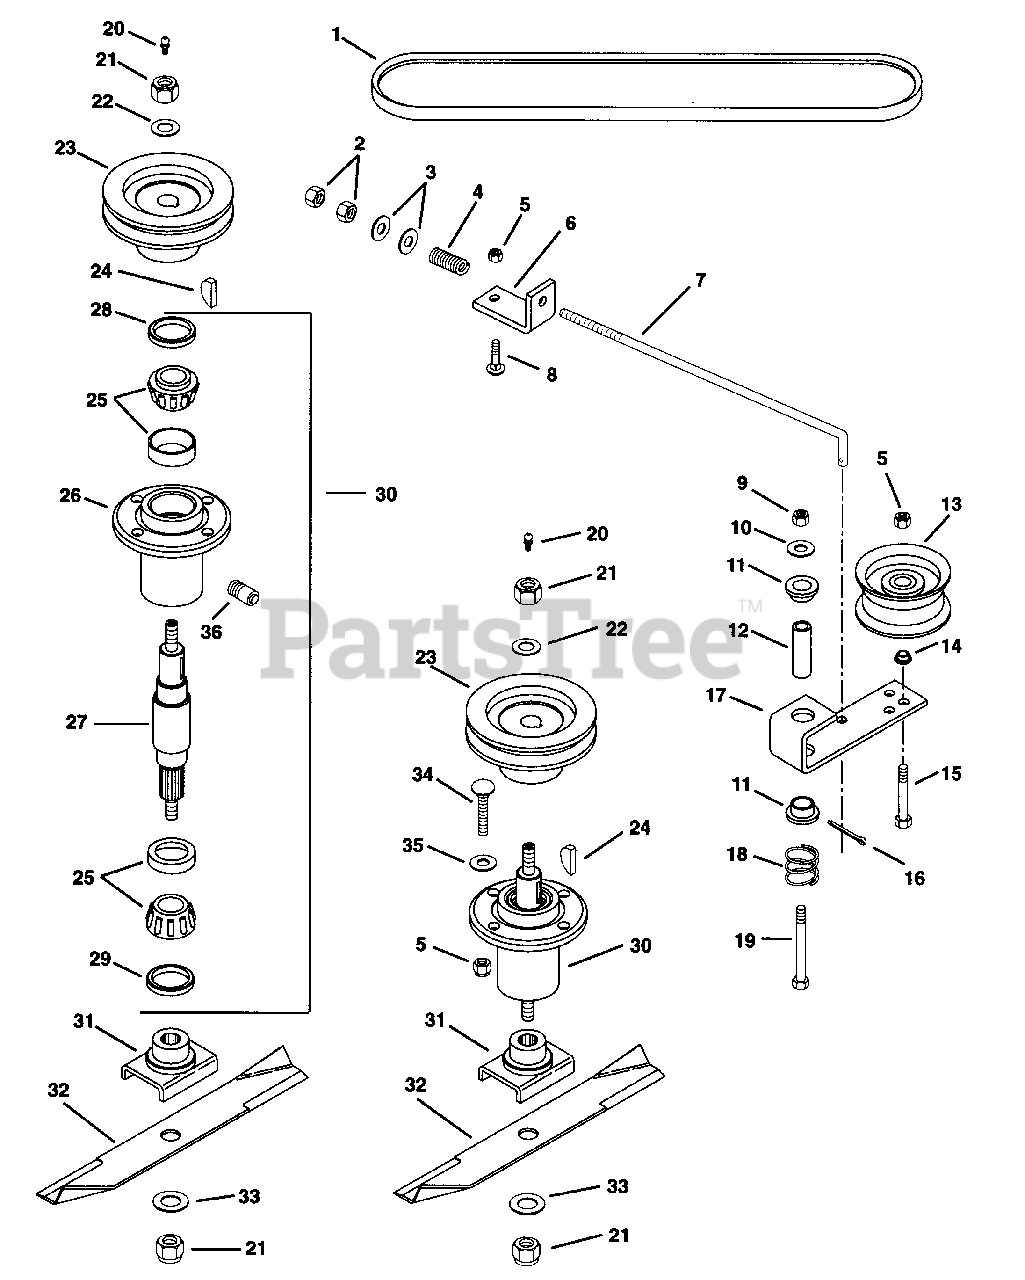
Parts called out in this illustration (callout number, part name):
1	V-Belt 4L-Section
2	Nut-Hex .375-24 Grade 2
3	Washer-Flat-Steel .406 x .812 x .065
4	Spring-Compression .125 x .78 x 1.00
5	Nut-Locking-Nylon .375-16 Grade 2
6	Bracket, Belt Tensioner
7	Rod, Idler 72" Mower
8	Bolt-Round Head Square Neck .38-16 x 1.0
9	Nut-Locking .50-13
10	Washer-Flat-Steel .531 x 1.250 x .100
11	Bushing-Flange .762 x 1.0 x .580 x 1.48
12	Bushing, Steel .560 x .750 x 2.44
13	Idler-Flat 4-6.87 x .38
14	Bushing-Flange .406 x .88 x .270 x .140
15	Bolt-Hex .38-16 x 2.25 Grade 5
16	Pin-Cotter .09 x .75
17	Arm, Idler Pivot
18	Spring-Compression .085 x .80 x 1.00
19	Bolt-Hex .50-13 x 3.25 Grade 5
20	Fitting-Lube 1/8
21	Nut-Locking-Nylon .625-11 Grade 2
22	Washer-Flat-Steel .687 x 1.312 x .150
23	Sheave
24	Key-Woodruff .25 x 1
25	Assembly, Bearing Cup & Cone
26	Bearing Housing
27	Shaft, Spindle
28	Seal 1.987 x 1.500 x .313
29	Seal 1.987 x 1.375 x .313
30	Service Kit Spindle Assembly
31	Weldment, Blade Cradle
32	Blade, 36" Mower
33	Washer-Flat-Steel .656 x 1.312 x .095
34	Bolt-Hex .38-16 x 1.25 Grade 5
35	Washer-Flat-Steel .500 x 1.250 x .083
36	Relief Fitting
